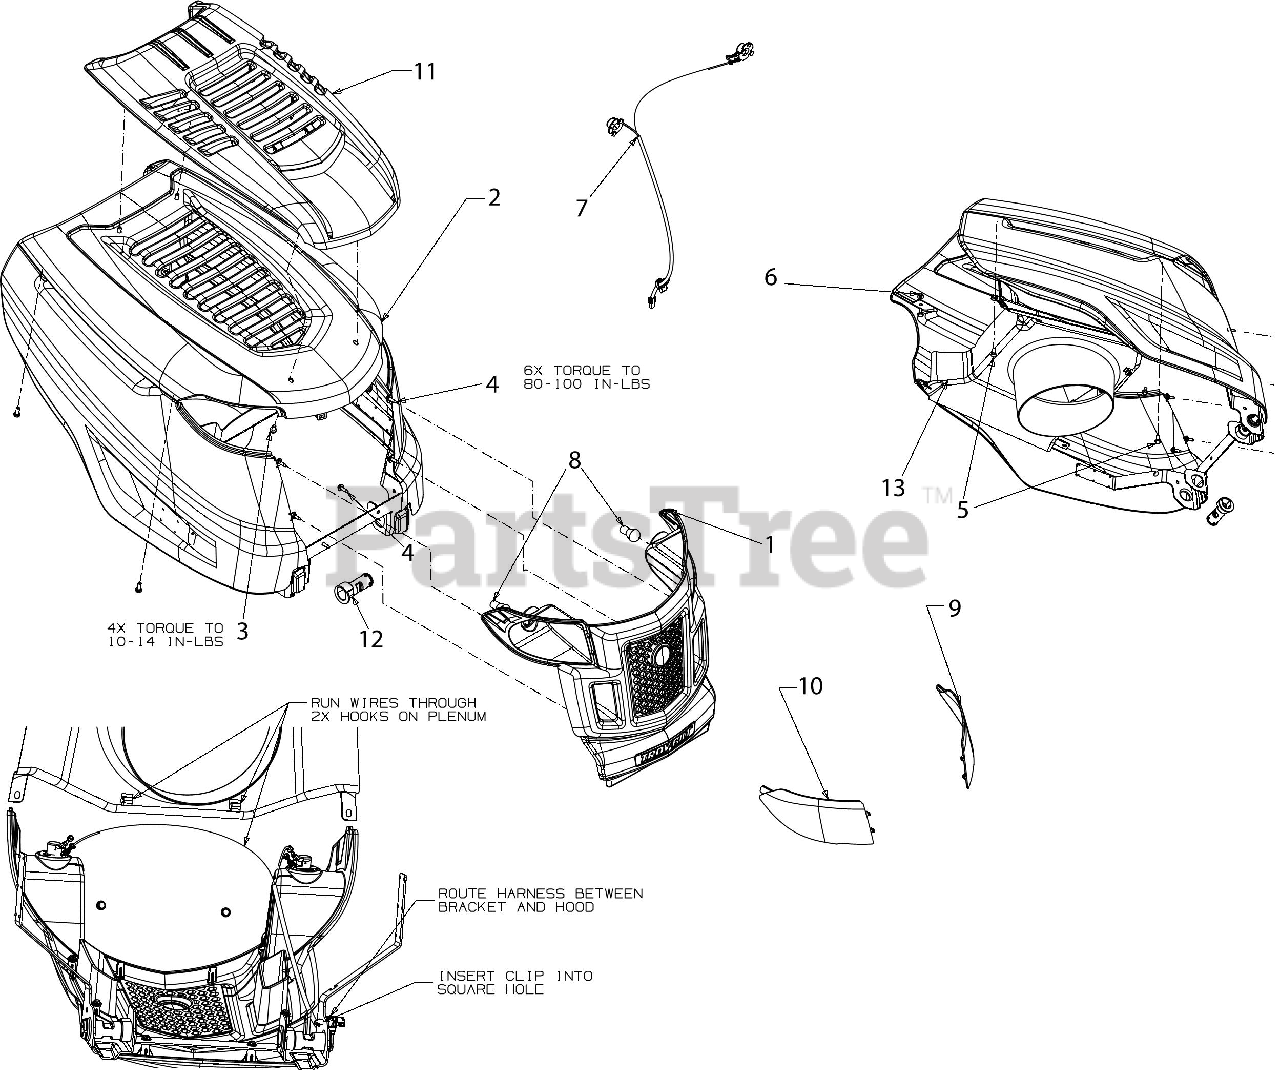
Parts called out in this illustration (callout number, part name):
1	GRILLE ASSEMBLY (TROY-BILT)
3	HEX SCREW 1/4-15 x .50
4	SCREW 1/4-10 x .750
5	SCREW 1/4-20 x .620 GR5
6	FLANGE LOCK NUT
7	HEADLIGHT HARNESS
8	MINIATUURE BULB 12V
12	HOOD PIVOT PIN
13	PLENUM (K-STYLE)
